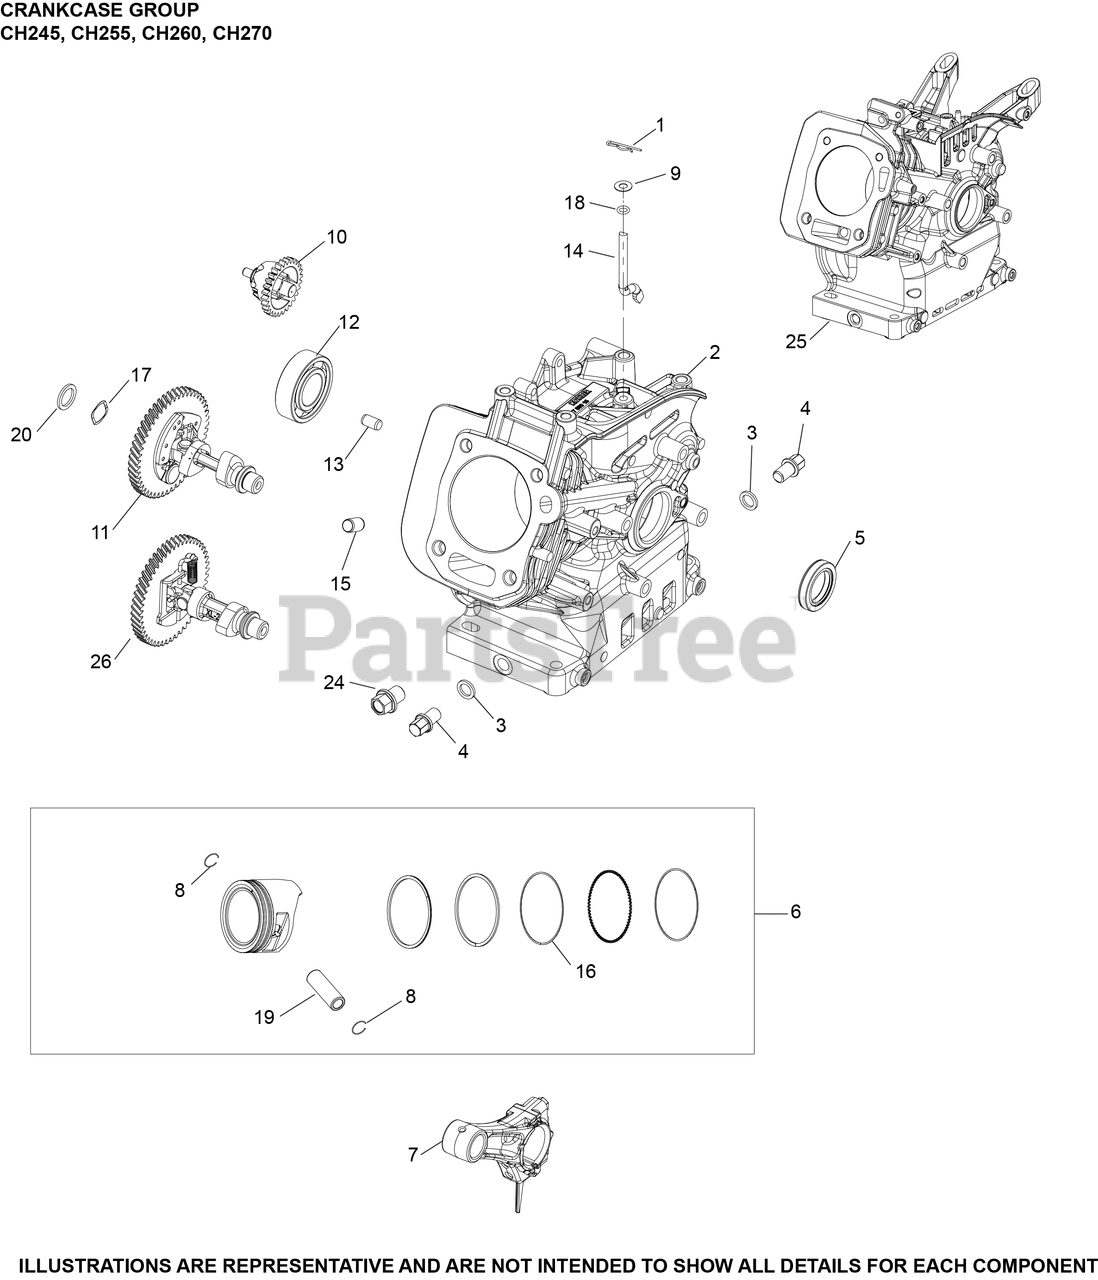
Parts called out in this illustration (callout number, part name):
1	CLIP, GOVERNOR SHAFT
2	CRANKCASE
3	WASHER, DRAIN PLUG
4	KIT, DRAIN PLUG
6	KIT, PISTON (STD)
7	ROD, CONNECTING ASSEMBLY
9	WASHER, FLAT (DIA 13MM O.D.) USE 14 468 30-S
10	GOVERNOR ASSEMBLY
14	SHAFT, GOVERNOR CROSS
15	DOWEL, CYLINDER HEAD-(#1438013S)
19	PIN, PISTON
